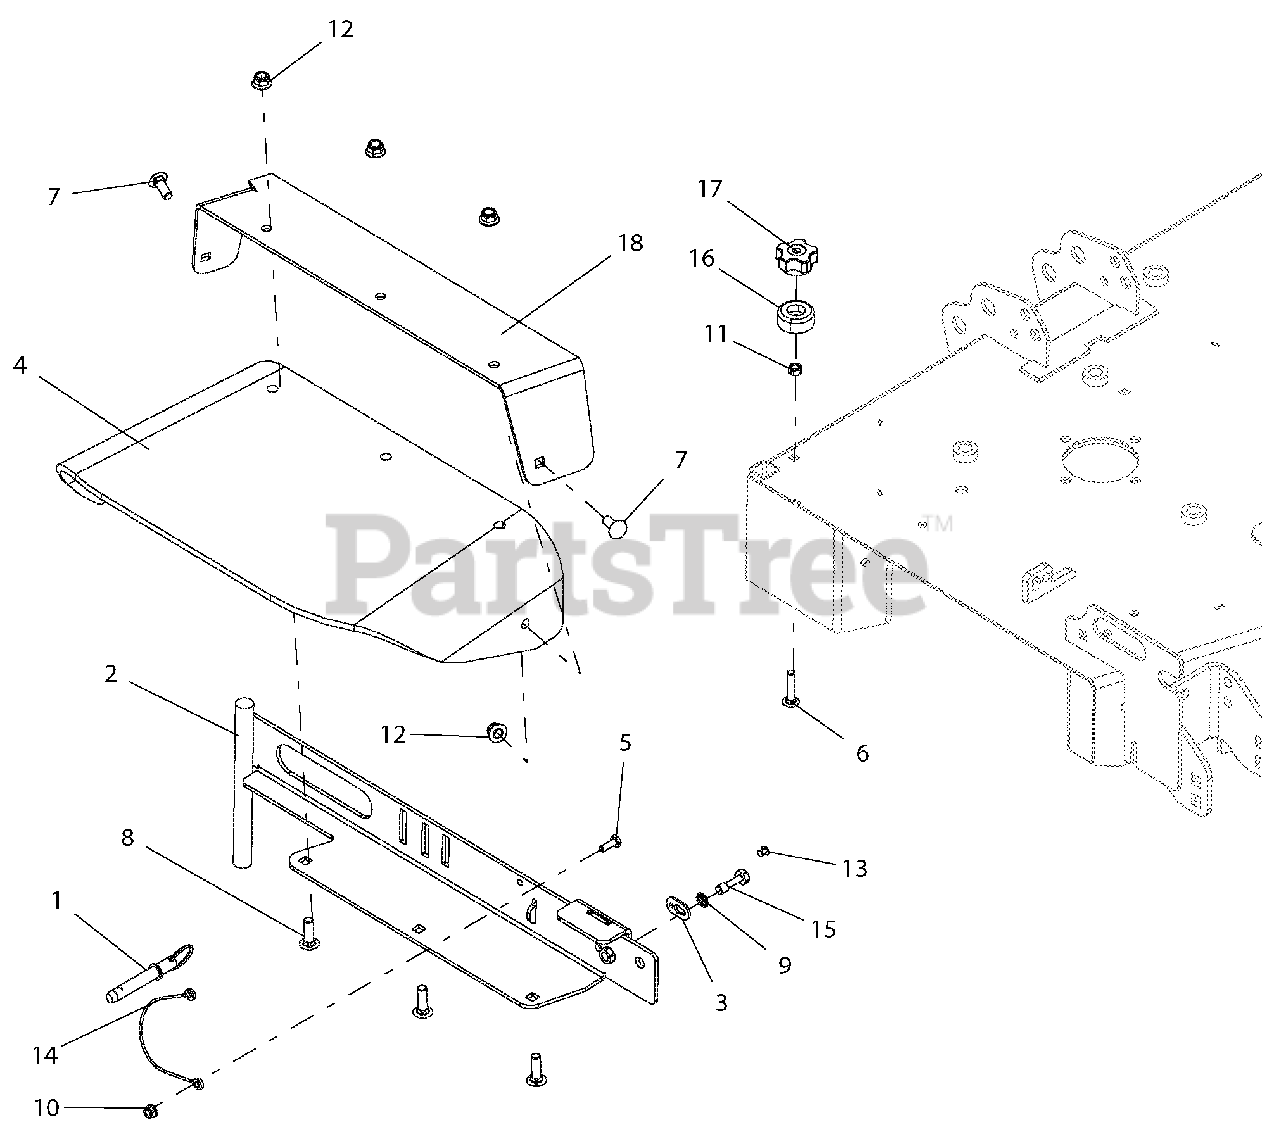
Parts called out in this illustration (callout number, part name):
1	PIN, .50 X 2.00 USABLE LG BALL
2	WLDMT, 52" DISCHARGE CHUTE MTG-CE
3	KEEPER, BOLT
4	CHUTE, RUBBER DISCHARGE
5	BLT-HEX .25-20X.75 GR5 YWZC
6	BLT-RDHDSQNK .31-18X1.50 G5 YWZC
7	BLT-RDHDSQNK .38-16X1.00 G5 YWZC
8	BLT-RDHDSQNK .38-16X1.25 G5 YWZC
9	LOCK, WSHR-EXT 0.391 X 0.628 X 0.036 YWZC
10	NUT-LK-NYL-FLG .25-20 YWZC
11	NUT-LK-CTR .31-18 YWZC
12	NUT-LK-NYL-FLG .38-16 YWZC
13	RVT-POP .187x.250 (#64) YWZC
14	LANYARD, 12"
15	BLT-HEX .38-16X1.25 GR5 CAP .37
16	BUMPER, RECESSED 1.50 X .63 W/.31 HOLE
17	KNOB, CLAMPING
18	KIT, PT DISCH CHUTE SUPT W/SAFETY DECALS-RED
